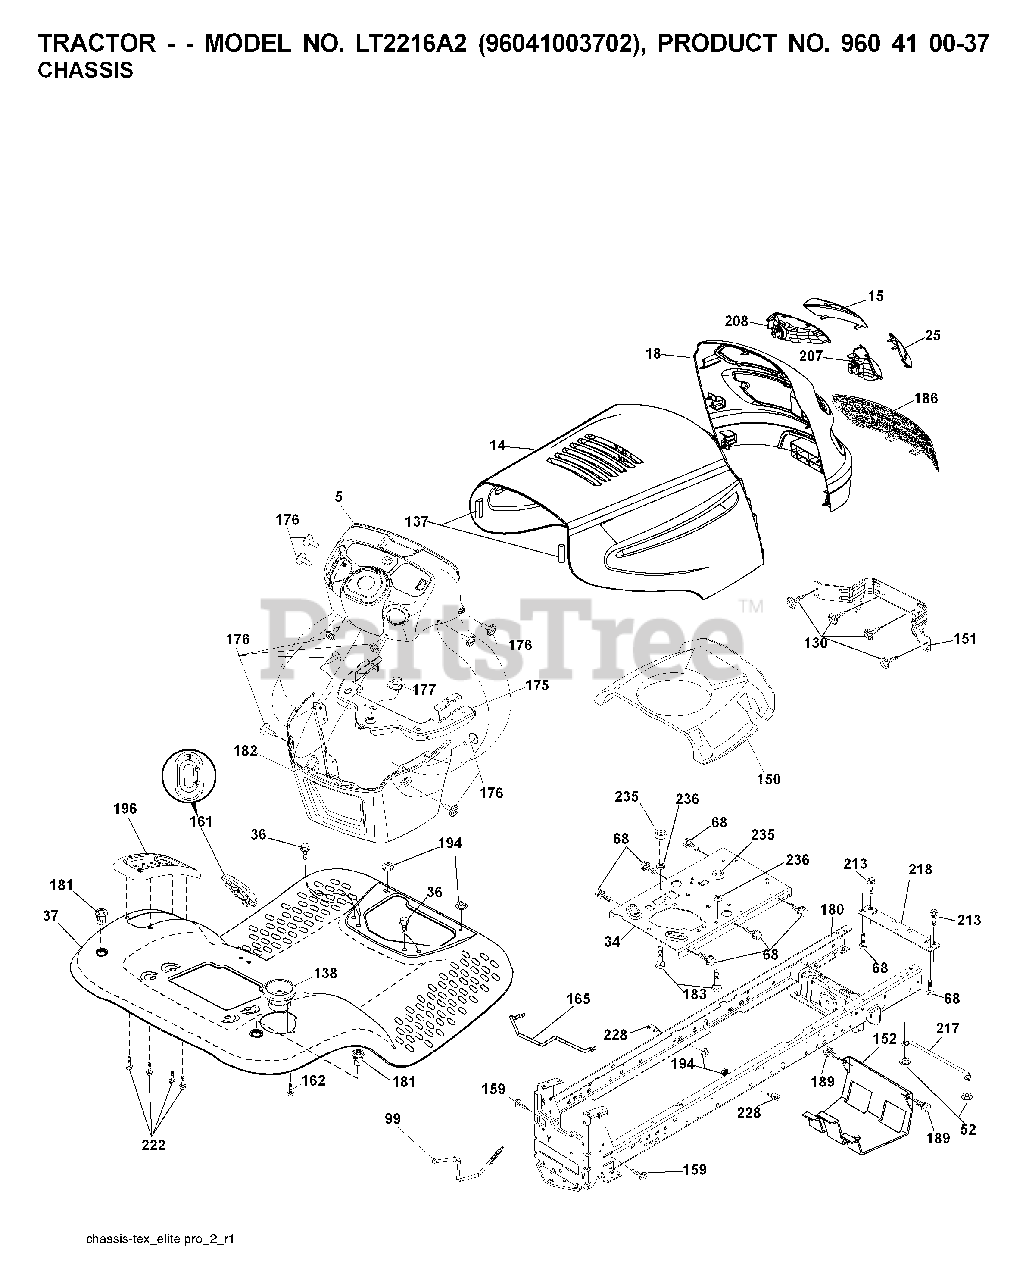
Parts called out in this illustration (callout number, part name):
34	PLATE.ENGINE.WELDED.CHASSIS
36	SCREW 5/16"
52	LOCKNUT
130	SCREW.#10 X 0.750.BOS THREAD
137	BUMPER.HOOD.LARGE.1.75"
138	CUPHOLDER.TL.TEX.BLACK
150	DUCT.INTAKE.AIR.KAW
151	BRACKET PIVOT
152	SHIELD BROWNING
159	SCREW, 3/8-16X3/4
161	WINDOW.FUEL.LT.TEX.BLACK
162	SCREW.HI-LO.CONSOLE
165	SUPPORT.TANK.REAR.W/TE
175	CROSSMEMBER.LT
176	SCREW.#10-24X5/8.RN.QU
177	BUSHING STEERING
180	CHASSIS
181	FEND/FTRST.PCH.CPH.NFW
182	DASH.LOWER.LT.CCS
183	BOLT.5/16-18X1-1/4 FULL.THREAD
189	SCREW
194	NUT LOCK HEX FLANGE 5/16-18
196	CONSOLE.ASM.DECK.LIFT.TLT.BLAC
207	BEZEL GRILL RH
208	BEZEL GRILL LH
213	BOLT
217	ROD.PIVOT.HOOD
218	X-PIECE.HOOD.STOP.NON/
222	SCREW.1/4-20X5/8
228	STUD.FASTNER.W/ANTI-ROTATE
235	SPACER FENDER
236	NUT.CENTERLOCK.5/16-
